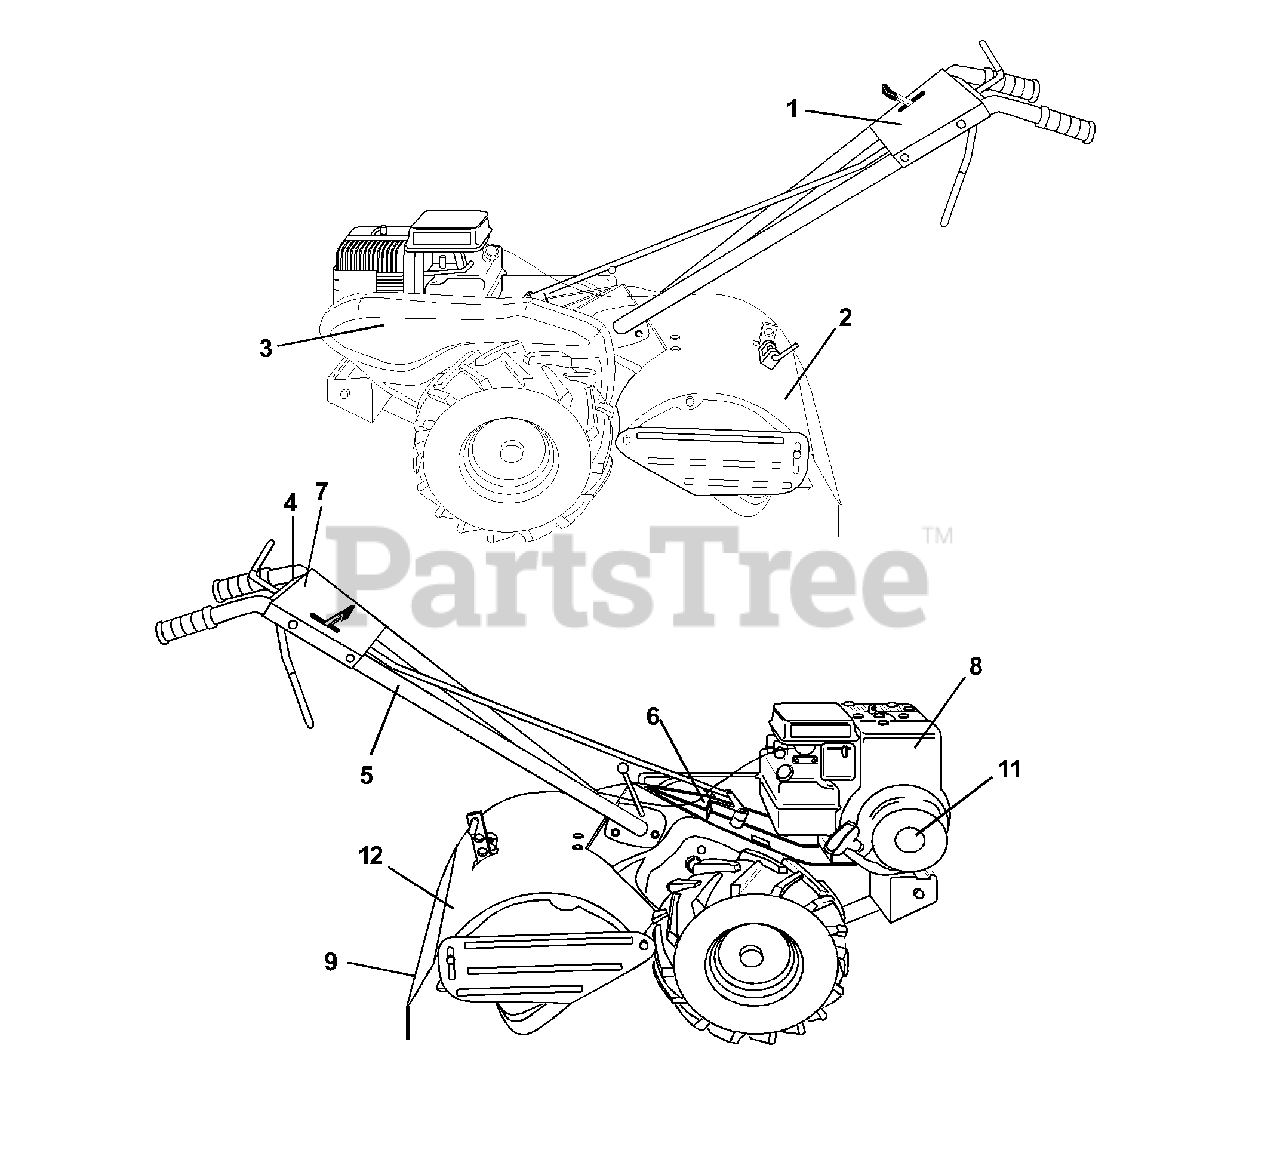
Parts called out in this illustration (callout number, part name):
1	Decal, Logo
2	Decal, Description
3	Decal, Logo
4	Decal, Instruction, Tilling
5	Decal, Hand Placement
6	Decal, Shift Indicator
7	Decal, Pnl Cntrl Reverse
8	Decal, Briggs & Stratton
9	Decal, Warning, Rotating Tines
11	Decal, 5 HP
12	Decal, Warning Till
